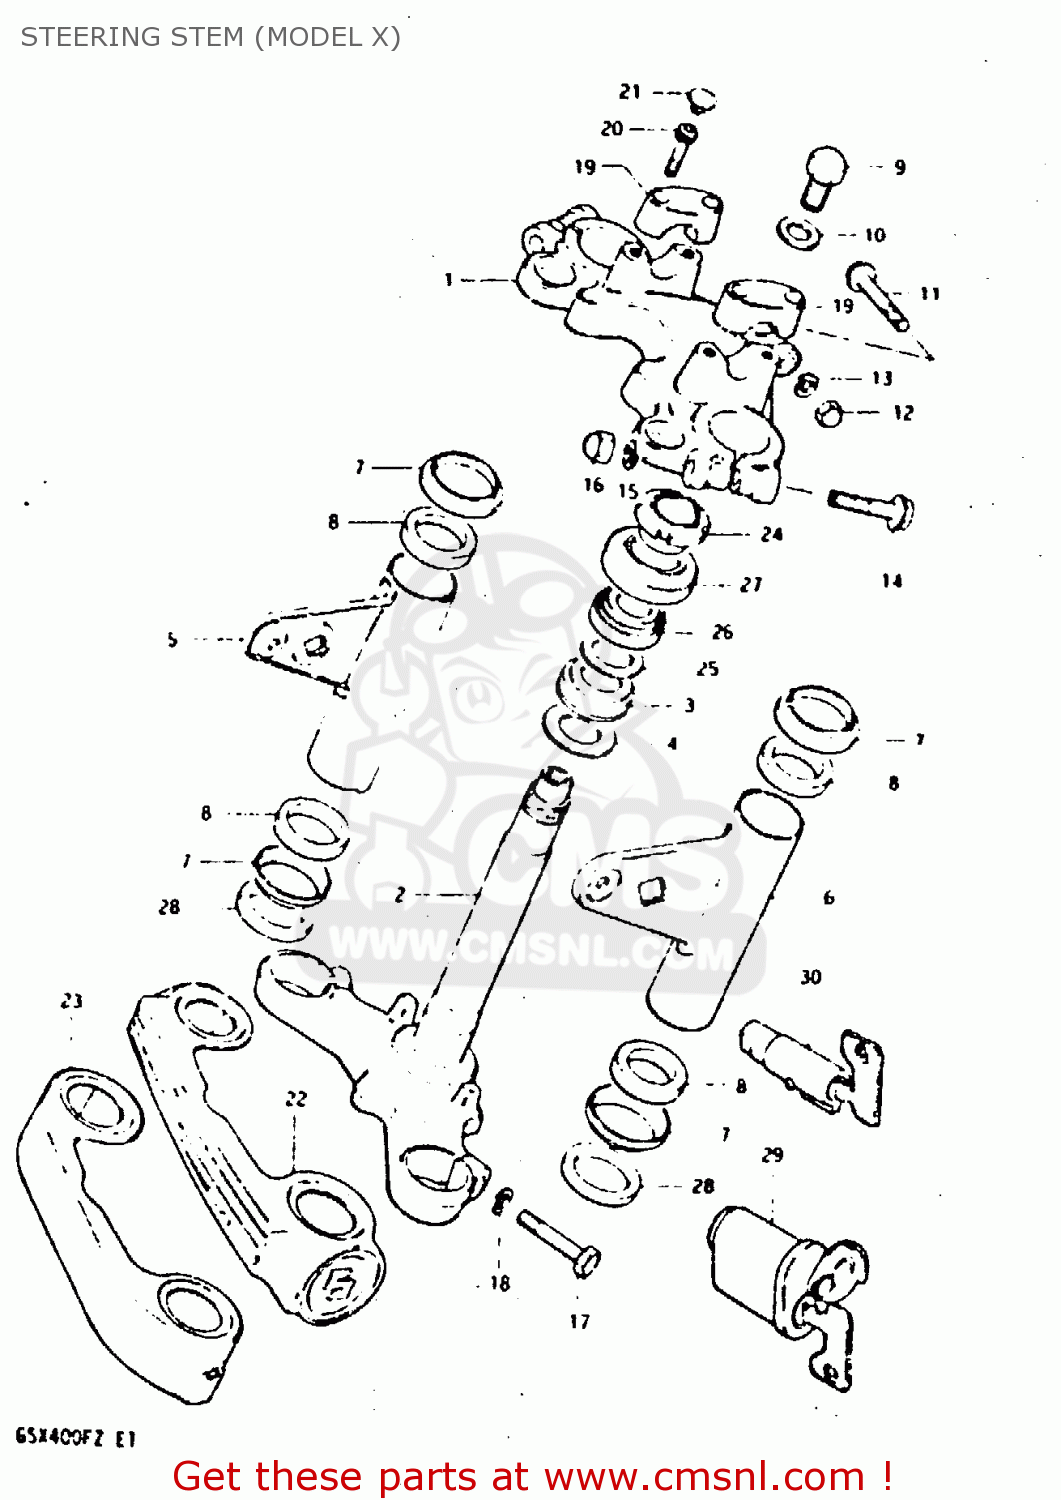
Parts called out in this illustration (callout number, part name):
1	HEAD,STEERING STEM
2	STEM,STEERING
3	BEARING
4	WASHER,THRUST
5	BRACKET,HEADLAMP,RIGHT
6	BRACKET,HEADLAMP,LEFT
7	CAP,HEADLAMP BRACKET
8	CUSHION,HEADLAMP BRACKET
9	BOLT(12X20)
10	WASHER
11	BOLT
12	NUT,M8X1.25X12
13	LOCK WASHER
14	BOLT 10X55
15	LOCK WASHER
16	NUT
17	BOLT 10X40
18	LOCK WASHER
19	HOLDER,HANDLEBAR(BLACK)
20	BOLT
21	CAP(OD:14.5)
22	COVER, FRONT FORK
24	NUT,STEERING STEM
25	WASHER(18.5X24X1)
26	TAPER,ROLLER BEARING
27	DUST SEAL,STEERING,UPPER
